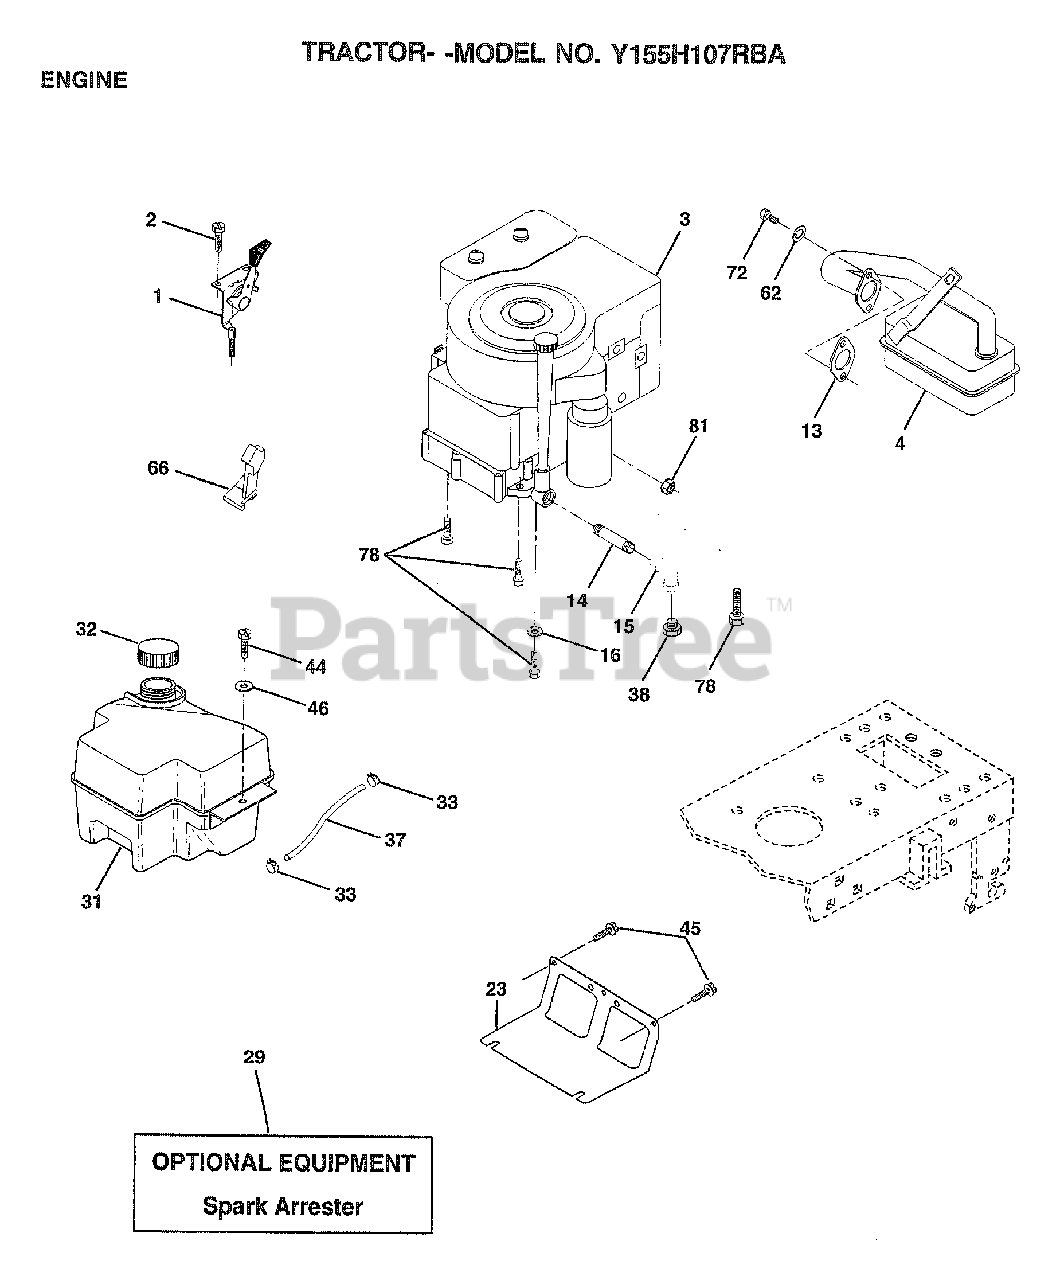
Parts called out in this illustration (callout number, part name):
1	CONTROL.THTL.23.5
2	SCREW LT
4	MUFFLER
14	PIPE NIPPLE
15	ELBOW
16	LOCKWASHER
23	SHIELD BROWNING
31	TANK.FUEL.FRONT.
32	CAP ASM FUEL
33	HOSE CLAMP
37	LINE FUEL
44	SCREW
45	SCREW
46	WASHER
62	LOCKWASHER
66	"STOP,DASH THROTT"
72	SCREW
78	SCREW
81	NUT
